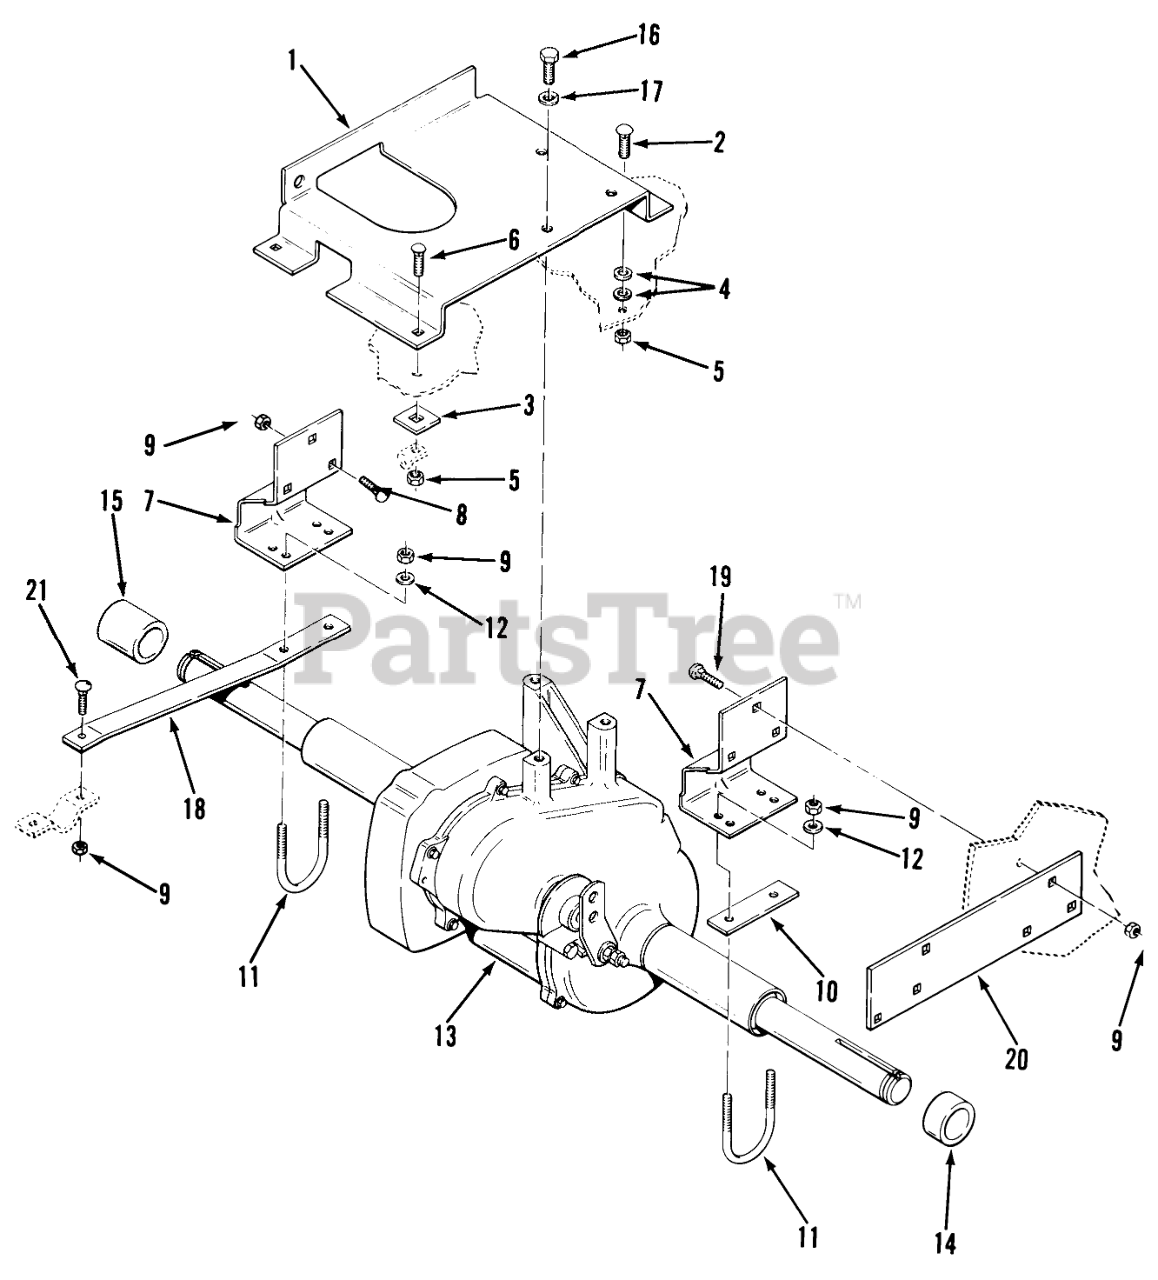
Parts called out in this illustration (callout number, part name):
1	Differential Support
2	Bolt-Carriage
3	PAD-SHORT R
4	WASHER 5/16 SAE
5	Nut
6	Bolt-Carriage
7	Bracket
8	Bolt
9	Nut
10	Spacer
11	U-BOLT AXLE MTG
12	WASHER 5/16 SAE
13	Sleeve
14	SPACER-AXLE LH
15	Axle Spacer RH
16	BOLT
17	LOCKWASHER
18	BRACE FRAME
19	Bolt
20	Frame Brace LH
21	Bolt-Carriage
